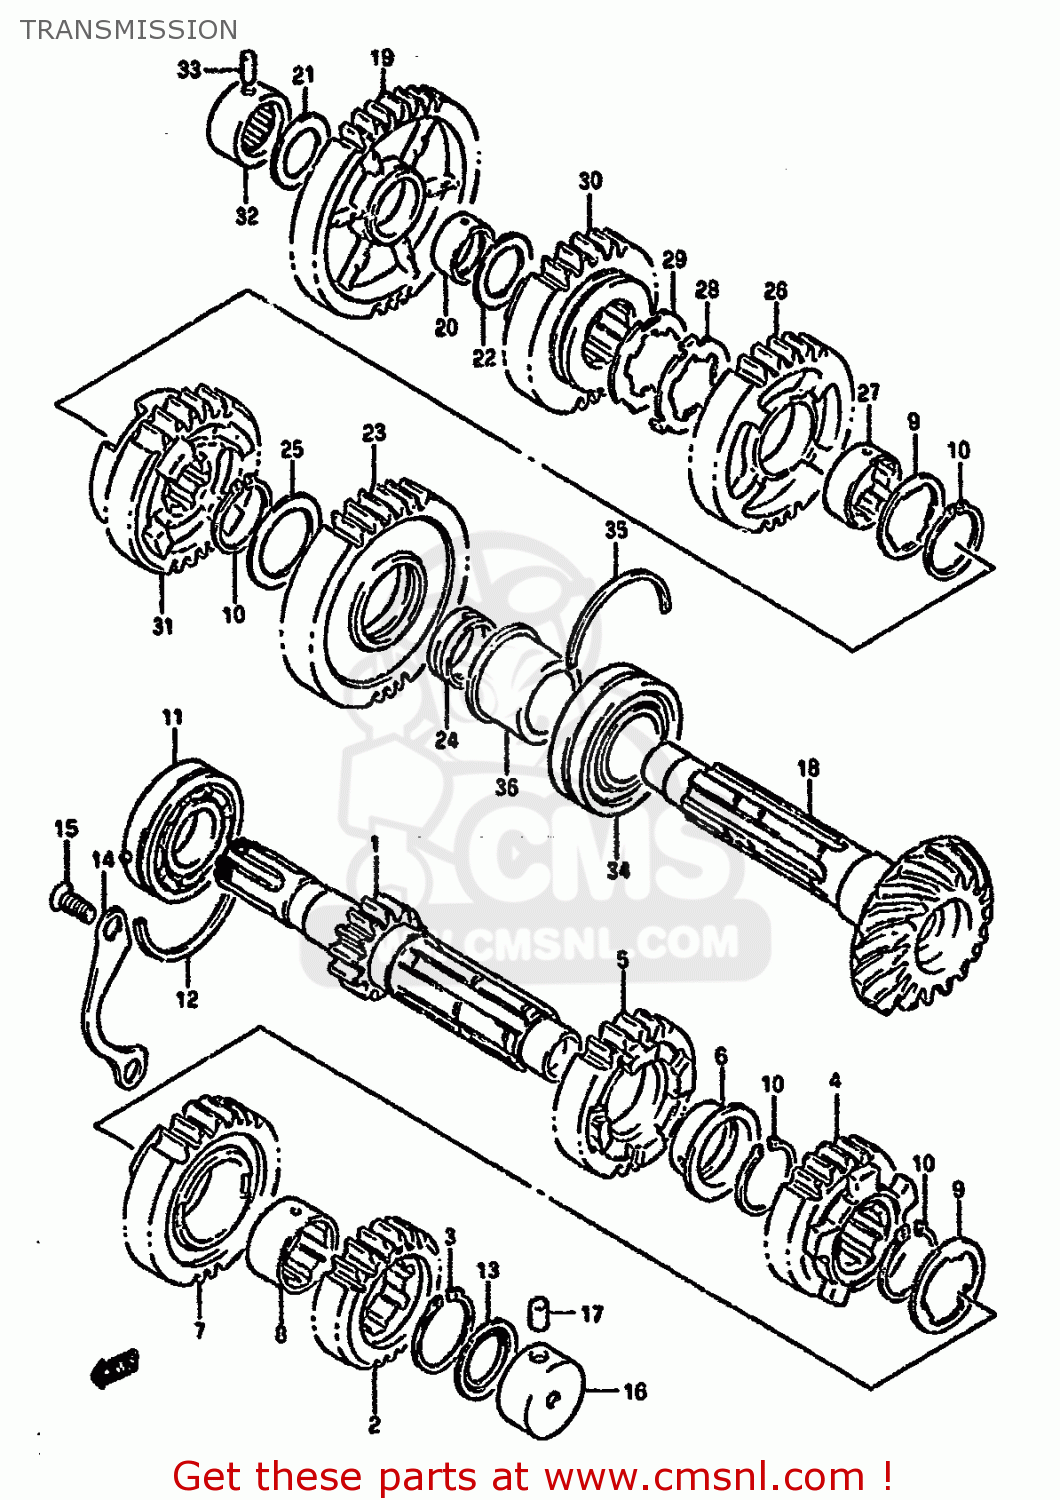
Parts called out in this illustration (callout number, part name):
1	SHAFT,COUNTER
2	GEAR,2ND DRIVE
3	CIRCLIP
4	GEAR,THIRD DRIVE
5	GEAR,4TH DRIVE
6	BUSH(28X32X2)
7	GEAR,FIFTH DRIVE
8	BUSH
9	WASHER,LOCK
10	CIRCLIP
11	BEARING(25X62X17)
12	C-RING
13	SEAL,OIL(20X31.2X2.7)
14	RETAINER,CNTR SHAFT BEARING
15	SCREW
16	BEARING(20X34X17.5)
17	PIN
18	SHAFT,DRIVE
19	GEAR,1ST DRIVEN
20	BUSHING
21	WASHER
22	WASHER
23	GEAR,2ND DRIVEN
24	BUSH(28X32X11)
25	WASHER, THRUST
26	GEAR,3RD DRIVEN
27	BUSH,3RD DRIVEN GEAR
28	WASHER,LOCK
29	WASHER,LOCK
30	GEAR,4TH DRIVEN
31	GEAR,5TH DRIVEN
32	BEARING(20X34X20)
33	PIN
34	BEARING(40X80X30.2)
35	C RING
36	SPACER,DRIVE SHAFT BEARING
